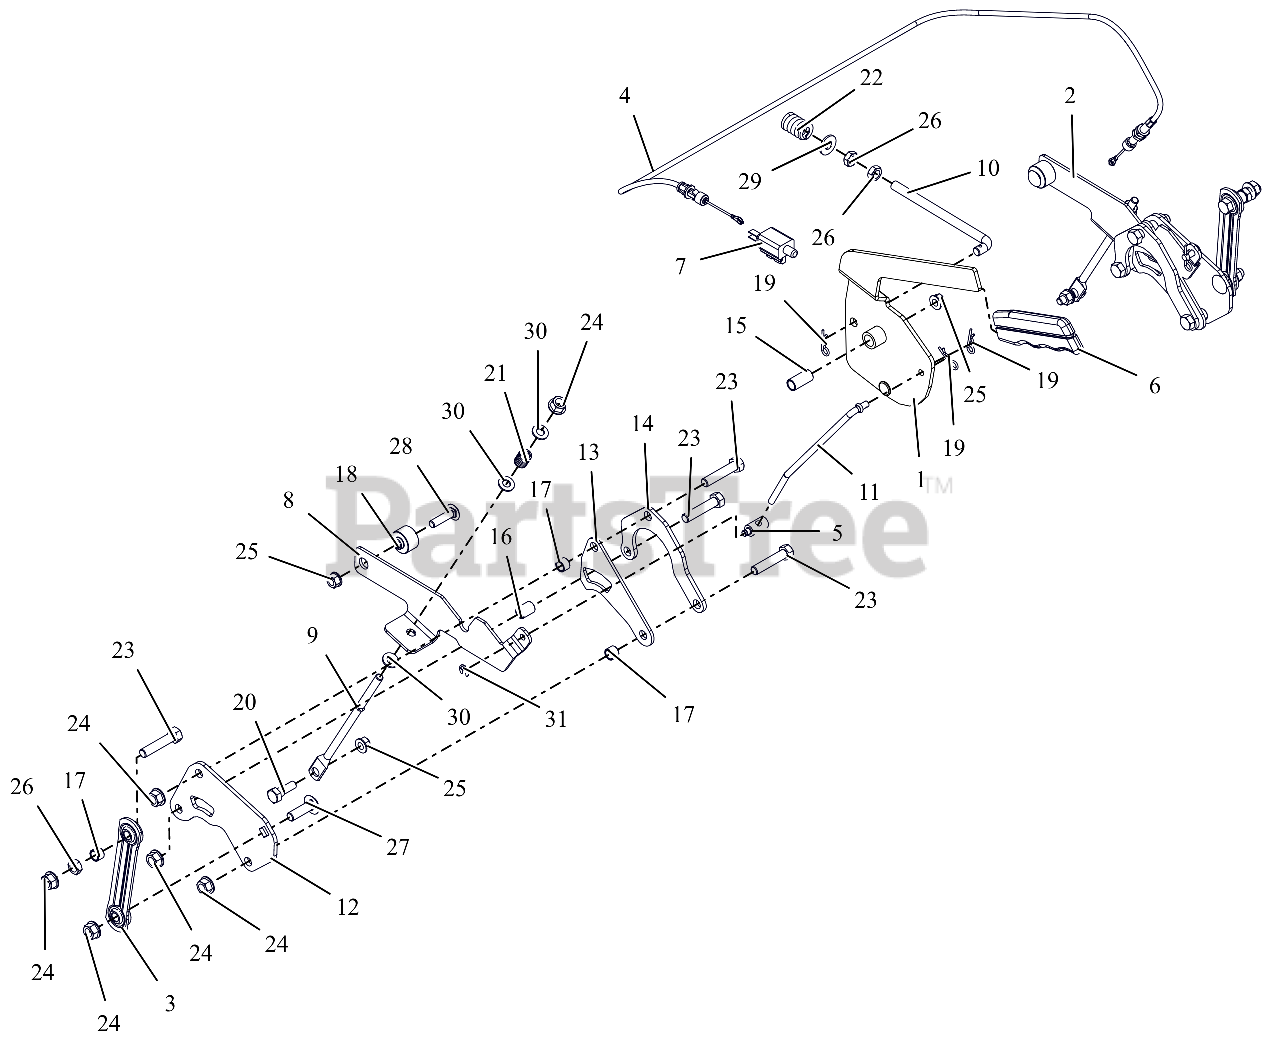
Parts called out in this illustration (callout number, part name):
1	LEVER, PARKING BRAKE
2	ARM, BRAKE - LH (W/PIN)
3	LINK, STAMPED STEERING
4	CABLE, BRAKE
5	TRUNION, 1/4-20
6	GRIP, PARKING BRAKE (YELLOW)
7	SWITCH, SINGLE POLE N.O.
8	ARM, BRAKE-RH
9	ROD, LINK - TRANSMISSION BRAKE
10	ROD, OVER CENTER
11	ROD, BRAKE LINK
12	BRKT, TRANSAXLE STEERING
13	BRKT-SPACER
14	PLATE, REAR REINFORCING
15	BSHG-SLV .385X.500X1.045
16	SPCR, SLV .385X.500X.652
17	SPCR, SLV .385X.500X.350
18	SPCR, FLANGE
19	PIN, HAIR #213 .08X1.19 ZCC
20	BOLT,SHLDR .38X.25 -.31-18X.75
21	SPRING, COMPRESSION
22	SG-COMP .187X.56X1.62
23	BLT, HEX .38-16X1.75 G5 ZCC
24	NUT-LK-TOP-FLG .38-16 ZC120
25	NUT-LK-TOP-FLG .312-18 GF ZCC
26	NUT-JAM .375-16 G2 ZCC
27	BLT,RHSSN .38-16X1.25 G5 ZCC
28	BTL,RHSSN .313-18 X 1.25 G5 ZCC
29	WSHR,FLT .375X.875X.083 ZCC
30	WSHR,FLT .344X.688X.065 ZCC
31	RG-RTNG-EXT .250X.025
